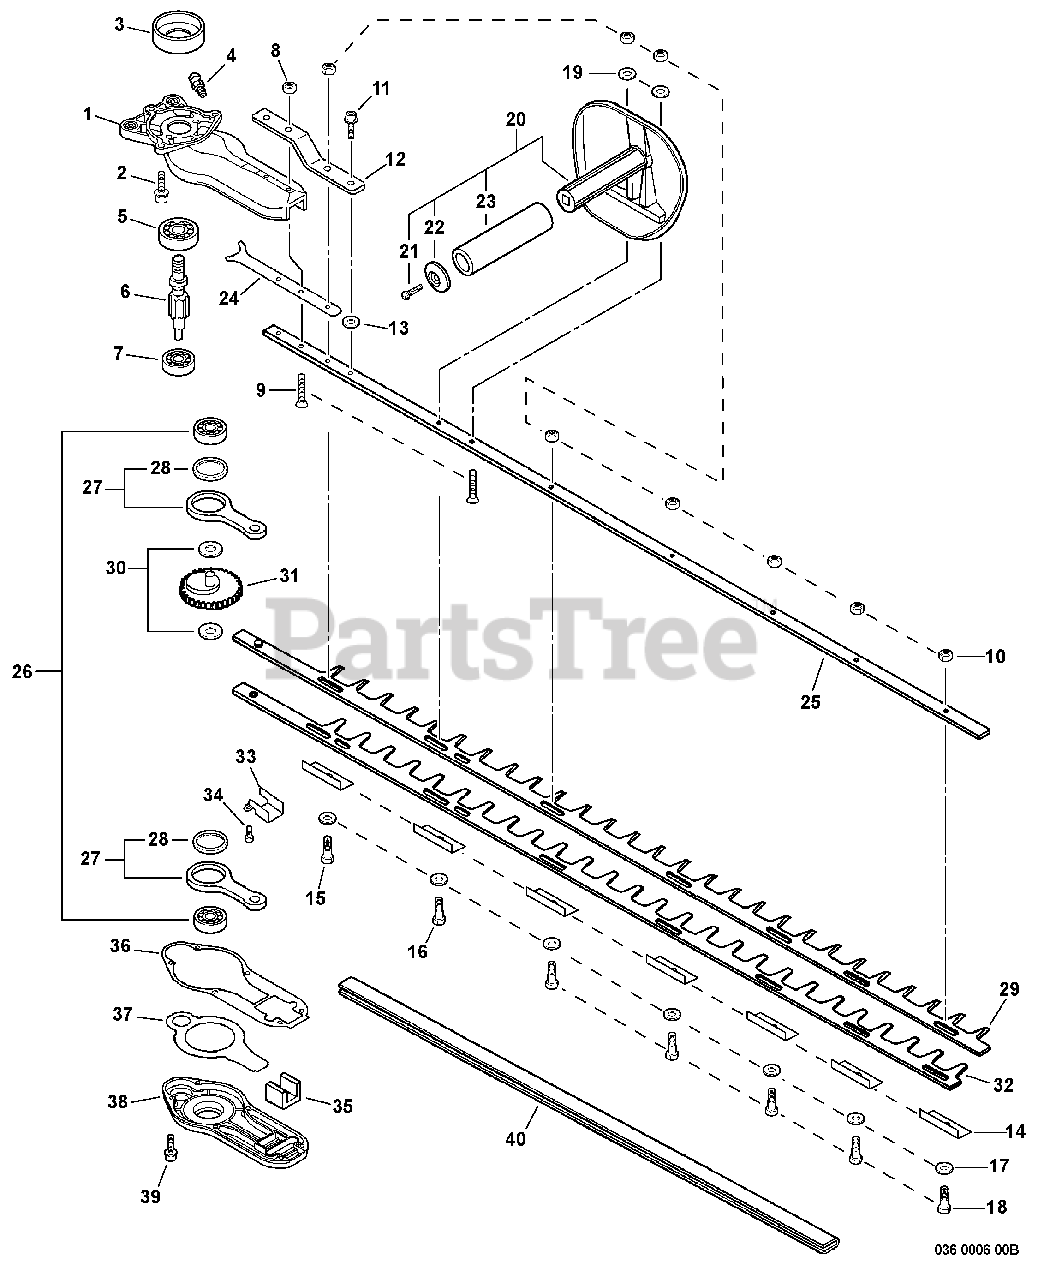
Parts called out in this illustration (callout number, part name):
1	CASE, GEAR - UPPER
2	SCREW - 6X18
3	DRUM, CLUTCH
4	FITTING, GREASE
5	BEARING, BALL - 6200
6	GEAR - SPUR
7	BEARING, BALL - 608ZZ
8	NUT - 6 -- FLANGE
9	SCREW - 6X30
10	LOCKNUT - 6
11	BOLT - 6X12
12	BRACKET, ANGLE
13	WASHER - 6
14	INSULATOR
15	BOLT - 6X35
19	WASHER - 6
20	HANDLE ASSY - FRONT
21	SCREW - 5X14
23	GRIP, HANDLE
25	SUPPORT, BLADE - 40" (101cm)
26	BEARING, BALL - 6200
27	ROD, CONNECTING
28	BEARING, NEEDLE
29	BLADE - 40" (101cm) -- UPPER
30	WASHER - 10
31	GEAR - SPUR
32	BLADE - 40" (101cm) -- LOWER
33	GUIDE, BLADE
34	SCREW - 4X16
36	GASKET, GEAR CASE
37	PLATE, GEAR CASE
38	CASE, GEAR - LOWER
39	SCREW - 4X16
40	COVER, BLADE
